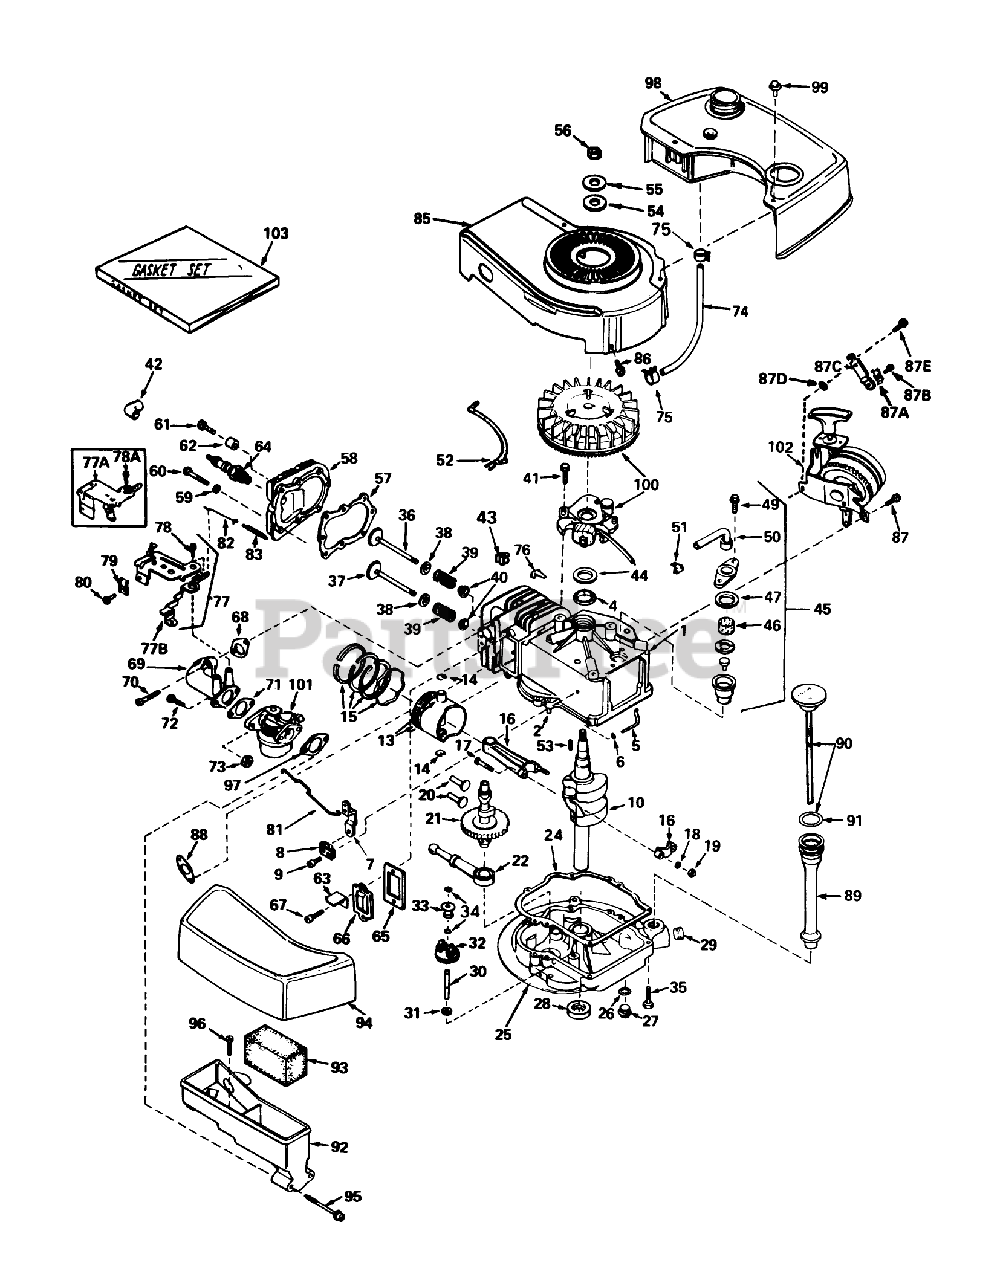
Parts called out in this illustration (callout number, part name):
1	Cylinder Assy. (Incl. Ref. #2, 4 105)
2	Pin-Dowel
4	OIL SEAL
5	Rod, Governor (Incl. No. 36)
6	Washer-Flat
7	Governor Lever
8	Clamp-Lever, Governor
9	Screw
10	Crankshaft
13	Piston Pin Assembly (Incl. 2 of No. 14) (.010 Oversize)
13	Piston Pin Assembly (Incl. 2 of No. 14) (.020 Oversize)
14	Ring-Retaining, Piston Pin
15	Ring Set Piston (Std.)
15	Ring Set Piston (.010 Oversize)
15	Ring Set Piston (.020 Oversize)
16	Rod Assy., Connecting (Incl. Ref. #17)
17	Bolt, Connecting
18	Washer
19	LOCKNUT
20	Lifter-Valve
21	Camshaft(Mech.Comp. Release)
22	Oil Pump ASM
24	Gasket, Mounting
25	Filter, Air Cleaner
26	Gasket-Oil Drain
27	Plug Oil Drain
28	Seal Oil
29	Plug Oil Drain
30	Shaft-Governor
31	Washer-Flat
32	Governor Gear ASM
33	Spool-Governor
34	Ring-Retaining
35	Screw (1/4-20 x 1-1/4)
36	Valve, Intake (Incl. Ref. #38, 39 40) (Std.)
36	Valve, Exhaust (1/32" Oversize) (Incl. Nos. 8, 9 10)
37	Valve, Exhaust (Standard) (Incl. Nos. 8, 9 10)
37	Valve, Exhaust (1/32" Oversize) (Incl. Nos. 8, 9 10)
38	Cap-Upper Valve Spring
39	Spring-Valve
40	Cap-Valve, Spring
41	Screw
42	Cover-Spark Plug
43	51004 GIL ROTARY TI
44	Gasket Stator
45	Breather Assy. (Incl. Ref. #46, 47, 49, 50 51 )
46	Element-Breather
47	Gasket-Breather
49	Screw, Hex Hd. w/Conical
50	Tube, Breaker
51	Clip, Breather
52	Wire Ground
53	Key-Flywheel
54	Washer Flat
55	Washer-Spring
56	Hex Nut
57	63573 GIL 42 SNWTHW
58	Head Cylinder
59	Washer
60	Screw
61	Screw Hex Hd. Cap
62	Space
63	Retainer Clip
64	Plug, Spark (J17LM or equiv.)
65	Gasket-Breather
66	Cover-Valve
67	Screw
68	Gasket, Intake
69	Pipe, Intake
70	Screw (1/4-20 x 1)
71	Gasket-Carburetor
73	Nut and Lock Washer (1/4-28)
74	Line-Fuel
75	Clamp-Line, Fuel
76	Clip-Wire
77	Control Assy., Speed (Incl. Nos, 76, 78 89)
77A	Control Assy., Speed (Incl. Nos, 76, 78 89)
77B	Lever Control
78	Screw, Hex Washer Hd Shoulder Self-Tap
78A	Screw (10-24 x 3/4)
79	Conduit
80	Screw (10-32 x 3/8)
81	Link Governor
82	Link Governor Spring
83	Spring Governor
85	Housing, Blower
86	Screw
87	Screw (1/4-20 x 1/2)
87A	Conduit
87B	Screw (10-32 x 3/8)
87C	Bracker
87D	Washer
87E	Screw (1/4-20 X 5/8)
88	Gasket Exhaust
89	Tube Fill
90	Dipstick, Oil (Incl. Ref. #101)(Twist Lock)
91	O-Ring
92	Body Air Cleaner
93	Filer, Air
94	Cove, Air Cleaner
95	Screw Fil Hd.
96	Screw, Hex Hd.
97	Gasket-Air Cleaner
98	Tank Fuel
99	Screw (10-32 x 35/64)
100	Magneto
101	Carburetor (Incl. No. 71)
102	Starter
103	53024/VAR.16HP O/P
